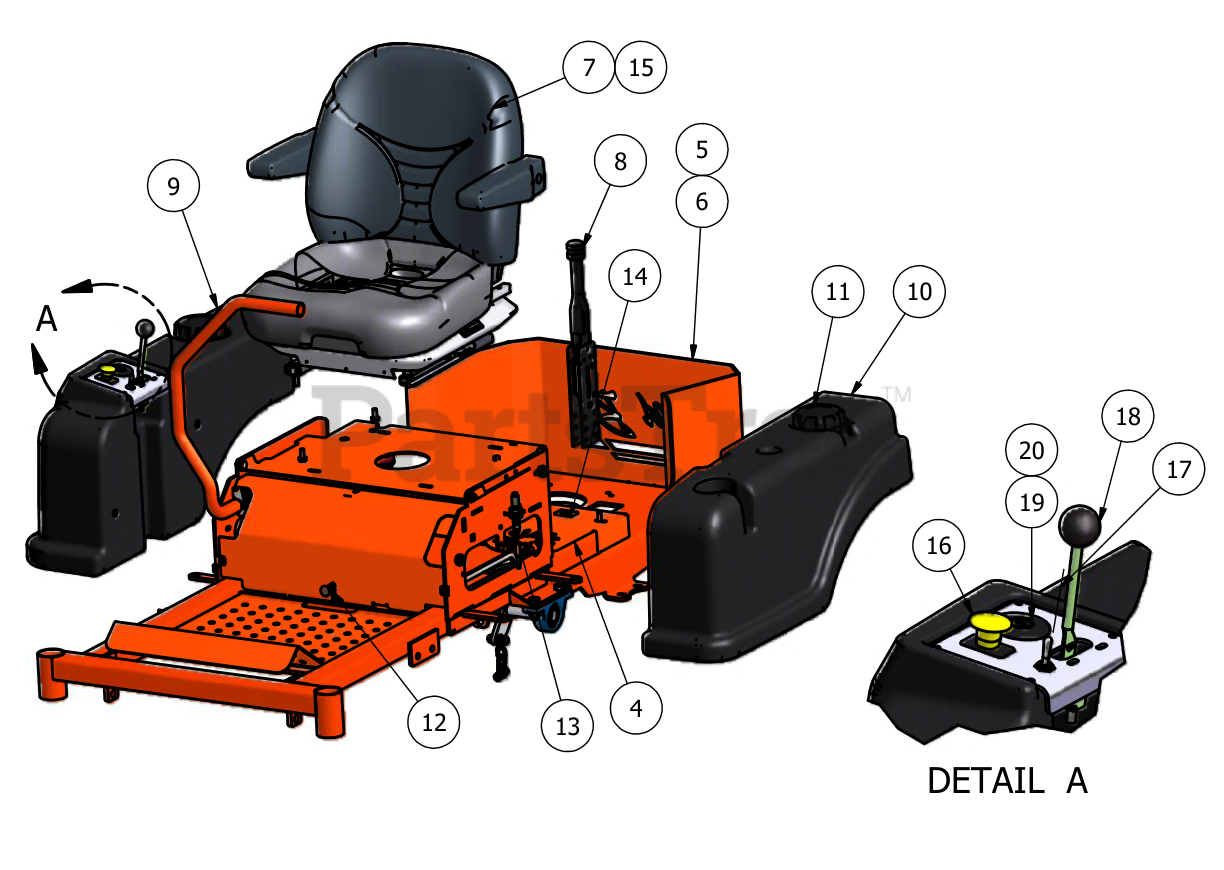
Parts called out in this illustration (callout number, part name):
1	ZT Floor Panel
2	Cooler Cover
3	Seat Mounting Plate
5	ZT Rear Plate 26hp
6	ZT Rear Plate 23hp
7	Seat Assembly
8	Hand Brake
9	Right Tank
10	Light Tank
13	Brake Cable
14	Tachometer
15	Seat Safety Switch
16	Pto Engager
